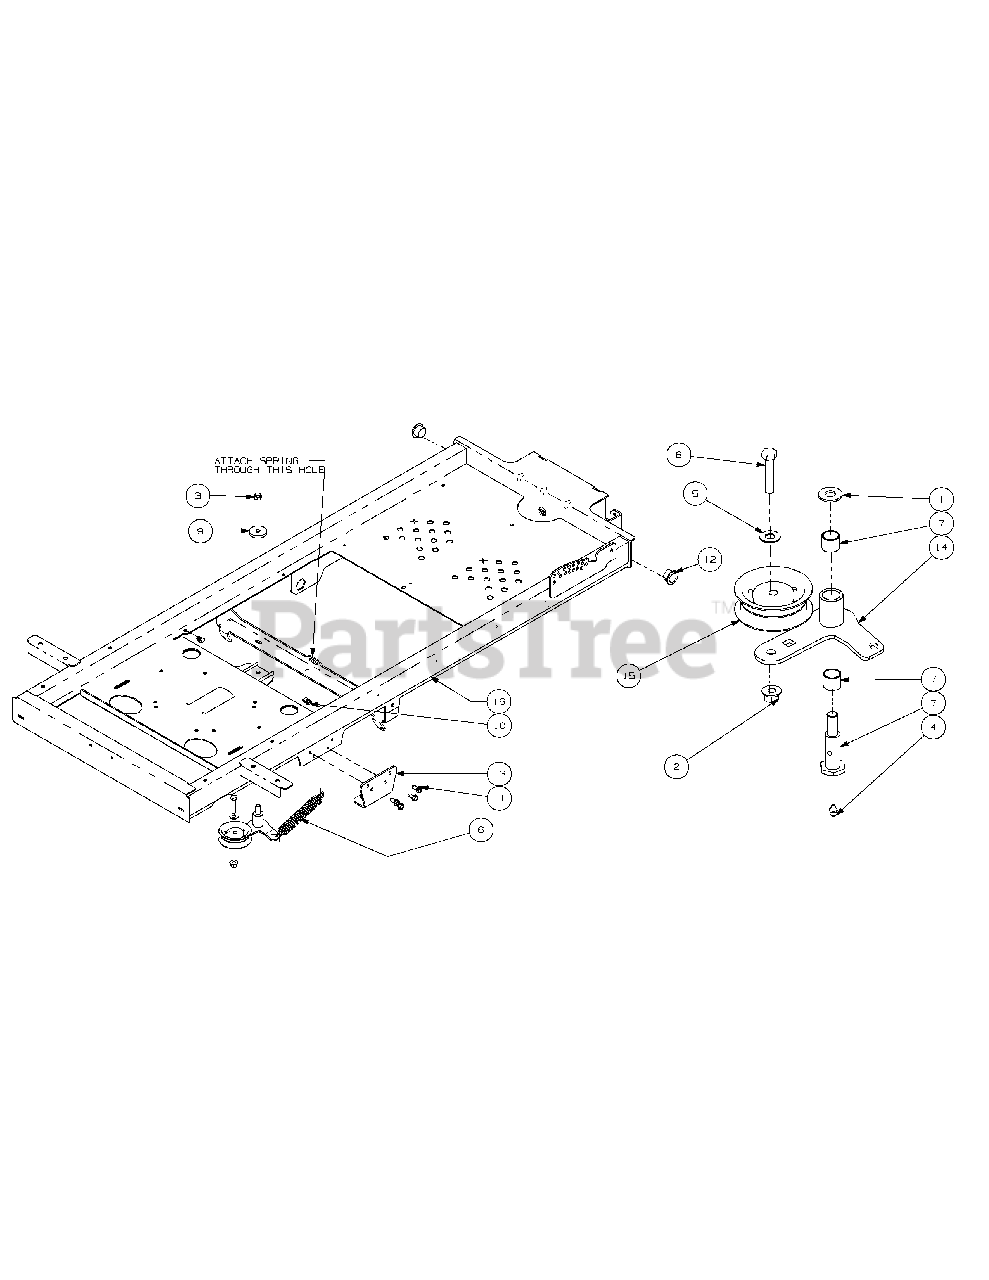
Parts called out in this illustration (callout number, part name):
1	Flat Washer, 3/8 zinc
2	Hex Nut, 3/8-16 Flange Lock
3	Nylock Nut, 7/16-14
4	Grease Fitting, 1/4-28 x 3/16
5	Washer, 3/8, SS
6	Extension Spring, 1.00 OD x 5.00 lg
7	Shoulder Bolt
8	Hex Cap Screw, 3/8-16 x 1-3/4
9	Flat Washer, 7/16 ID x 1.75 OD
10	U-Nut, 1/4-20
11	Self Tapping Screw 5/16-18 x .750
12	Bronze Bushing, 1.00 ID x 1.50 OD
13	Transmission Mounting Bracket
14	Idler Arm Assembly includes:
15	Flat Idler Pully
16	Frame Assembly Weldment
